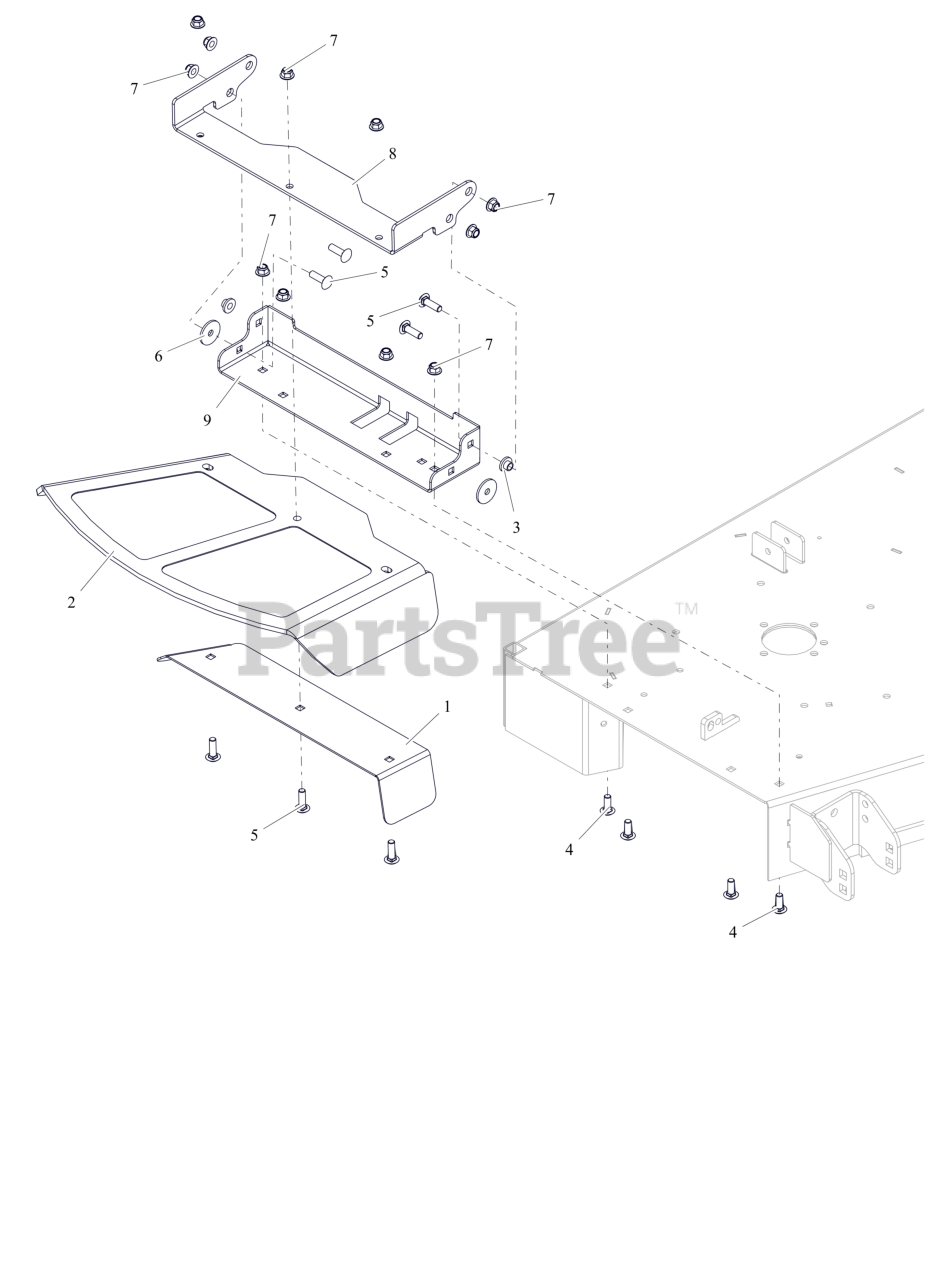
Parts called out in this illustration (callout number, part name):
1	PLT, DISCH. CHUTE CLMP-CE
2	CHUTE, FORMED RUBBER DISCHARGE
3	BSHG-FLG .385X.500X.875X.406
4	BLT,RHSSN .38-16X1.00 G5 ZCC
5	BLT,RHSSN .38-16X1.25 G5 ZCC
6	WSHR, FLT .380X1.50X.125 ZCC
7	NUT,NYL-FLG .38-16 GF ZCC
8	BRKT, CE CHUTE MTG (ORANGE)
9	WMT, DISCH. CHUTE-CE-W/SAFETY
